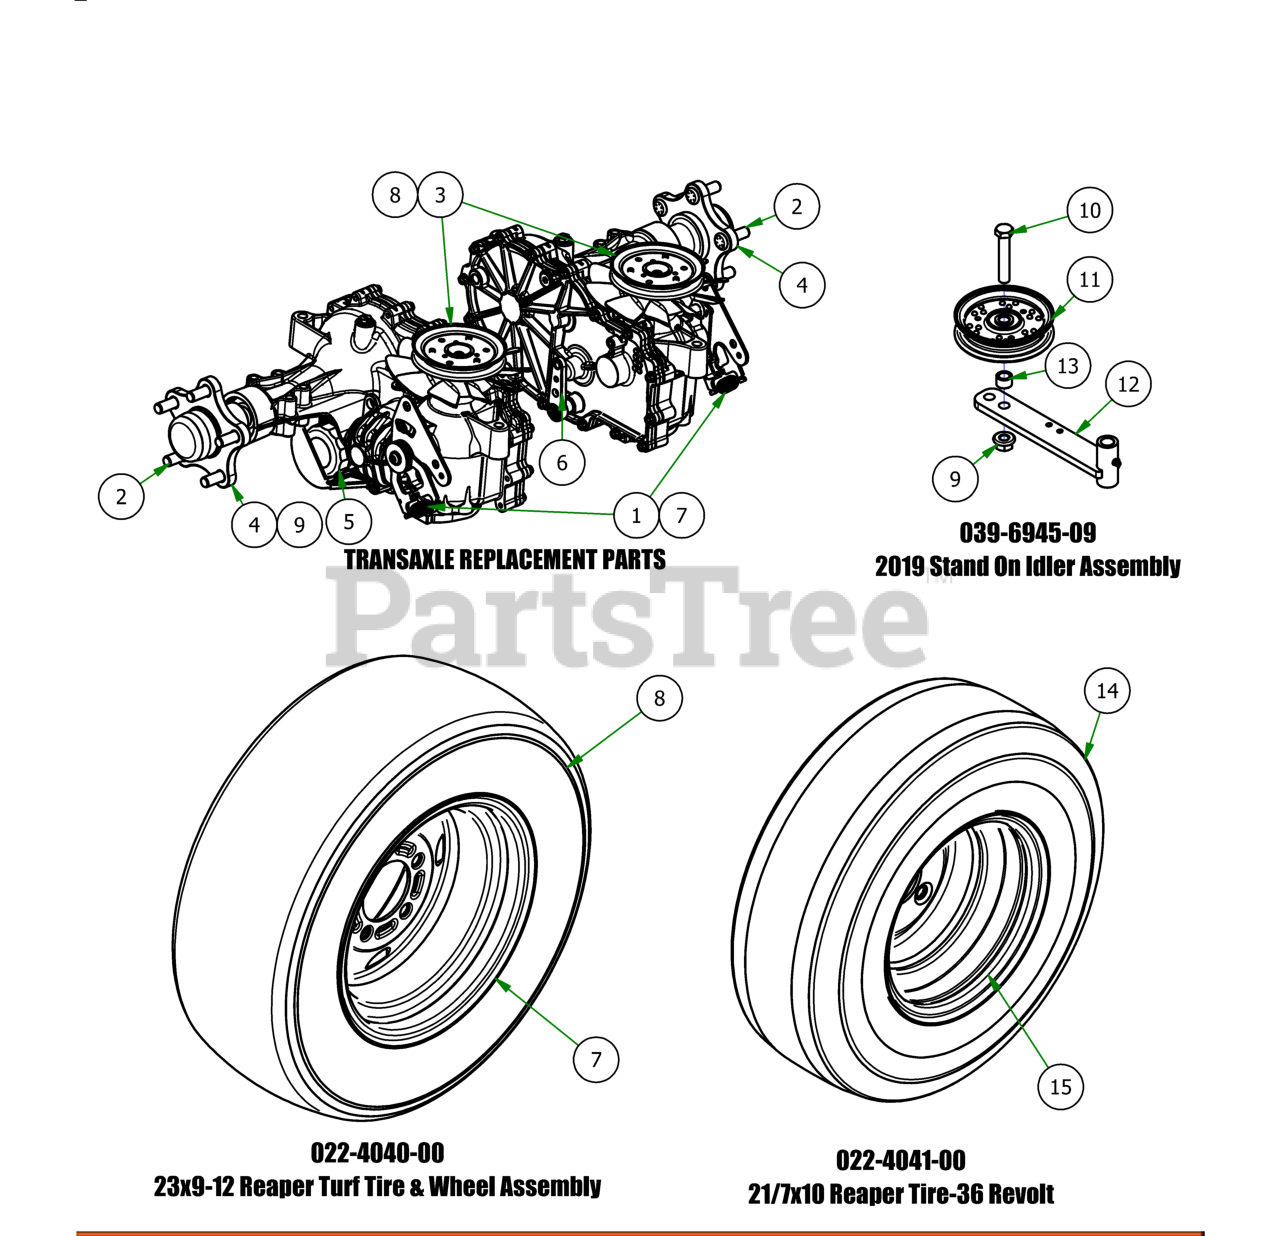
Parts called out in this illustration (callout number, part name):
1	Transaxle Spring (050-6000-00 & 050-6001-00)
2	Transaxle Wheel Studs (QTY 8 for 050-2065-00 & 050-2066-00)
3	Fan/Pulley Kit (050-6000-00 & 050-6001-00)
4	5 Bolt Hub Kit (050-6000-00 & 050-6001-00)
5	Transaxle filter
6	Transaxle Brake Lever
7	Transaxle Spring (050-2065-00 & 050-2066-00)
8	Fan/Pulley Kit (050-2065-00 & 050-2066-00)
9	Transaxle Hub (050-2065-00 & 050-2066-00)
